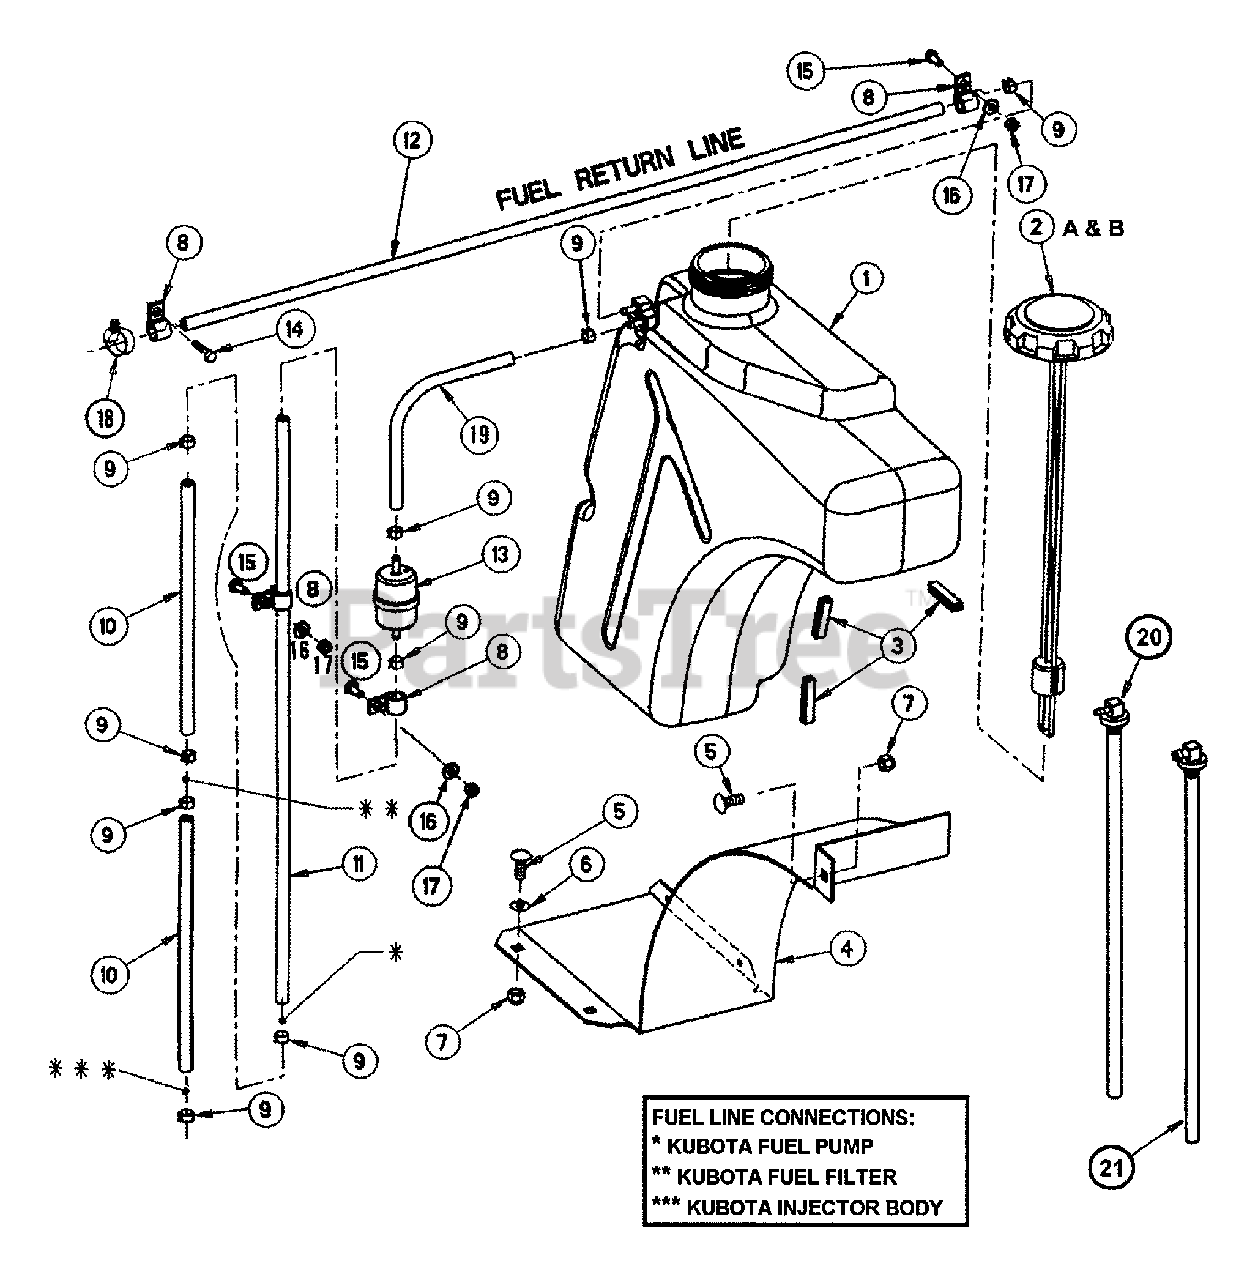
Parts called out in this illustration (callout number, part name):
1	TANK, Fuel
2A	ASSEMBLY, Cap/Gauge
2B	ASSEMBLY, Cap/Gauge (23 HP Gas Engine)
3	TRIM, 2 Inch
4	BRACKET, Fuel Tank Support
5	BOLT, Square Neck Carriage, Grade 5
6	RETAINER, 3/8" Bolt
7	NUT, 3/8-16 HEX NYLON LOCK
8	HARNESS CLIP, 3/8"
9	CLAMP, 9/16" Hose
10	HOSE, Fuel (8mm x 12")
11	HOSE, Fuel (8mm x 28")
12	HOSE, Fuel (8mm x 36") (21 HP Diesel Engine)
13	FILTER, Fuel, 5/16" Hose
14	SCREW, 5/16-18 x 5/8" Hex Washer Self-Tap
15	SCREW, 1/4-20 x 5/8" Hex Head Cap, Grade 5
16	WASHER, 1/4" Flat
17	NUT, 1/4-20 HEX NYLON LOCK
18	CLAMP, Hose 3/8"
19	HOSE, Fuel (6-1/2")
20	FUEL PICKUP (5/16")
21	FUEL PICKUP (5/32")
